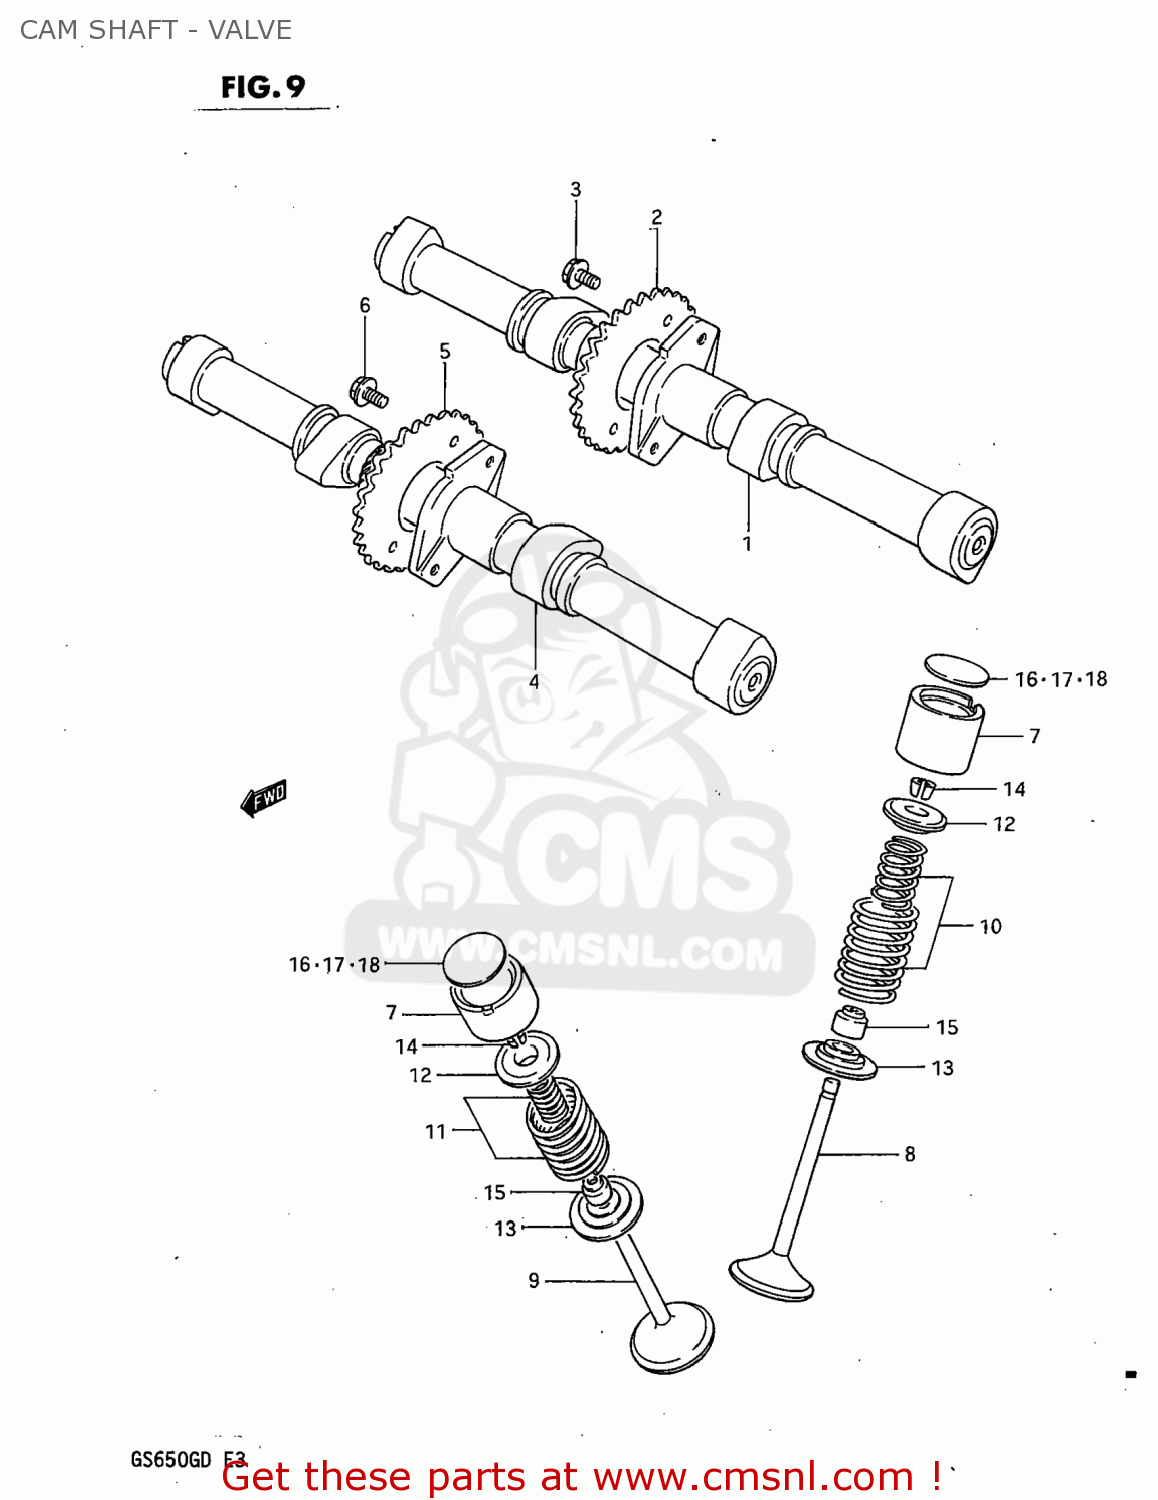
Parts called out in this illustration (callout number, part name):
1	CAMSHAFT,INTAKE
2	SPROCKET,INTAKE CAMSHAFT
3	BOLT(7X11)
4	CAMSHAFT,EXHAUST
5	SPROCKET,EXHAUST CAMSHAFT
6	BOLT(7X11)
7	TAPPET
8	VALVE,INTAKE
9	VALVE,EXHAUST
10	SPRING SET,VALVE
11	SPRING SET,EXHAUST VALVE
12	RETAINER,VALVE SPRING
13	SEAT,VALVE SPRING
14	COTTER VALVE
15	SEAL,OIL(7X14.4X9)
16	SHIM,TAPPET
17	SHIM,TAPPET
18	SHIM,TAPPET
19	SHIM SET,TAPPET
20	CASE
